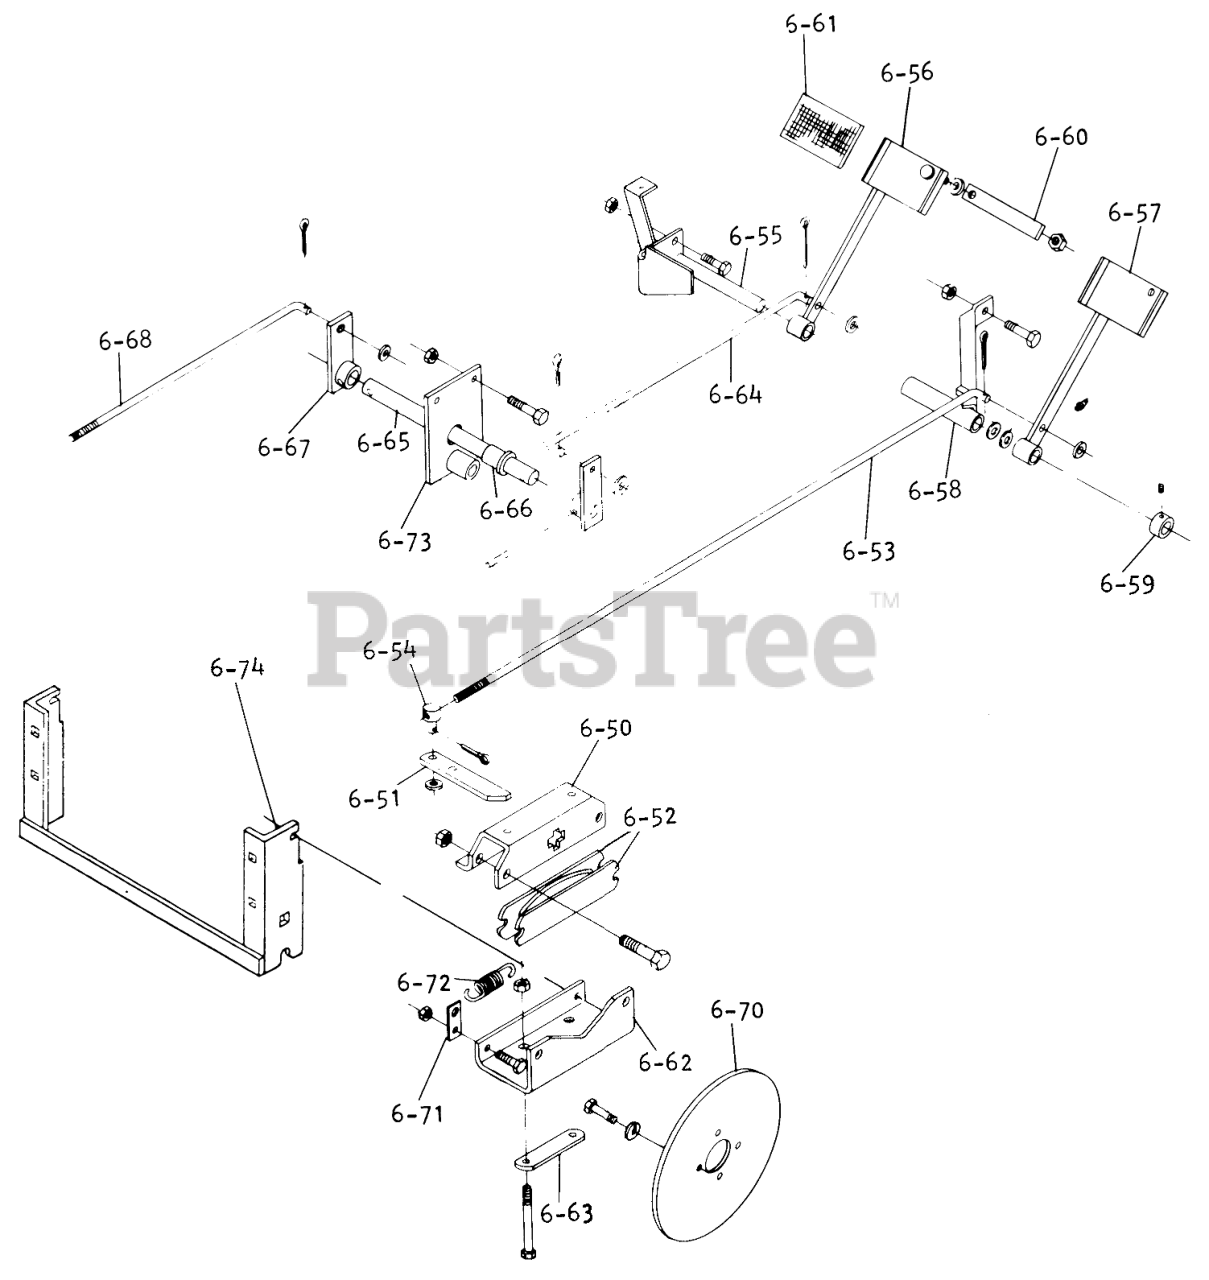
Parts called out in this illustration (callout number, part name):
6-50	Bracket-Secondary
6-51	Lever Assembly-Actuating
6-52	Plate Assembly
6-53	Rod Assembly
6-54	Trunnion
6-55	Pedal Pivot Assembly
6-56	Pedal-L.H.
6-57	Pedal-R.H.
6-58	Brace Assembly
6-59	Collar
6-61	Brake Pedal Pad
6-62	Plate-Brake Mounting
6-63	BRACKET-REAR LINK MOUNTING
6-64	Rod Assembly
6-65	Shaft
6-66	BEARING
6-67	Arm Assembly
6-68	Rod Assembly
6-71	Plate-Spring Anchor
6-72	SPRING
6-73	Support Assembly
6-74	Bracket Assembly
